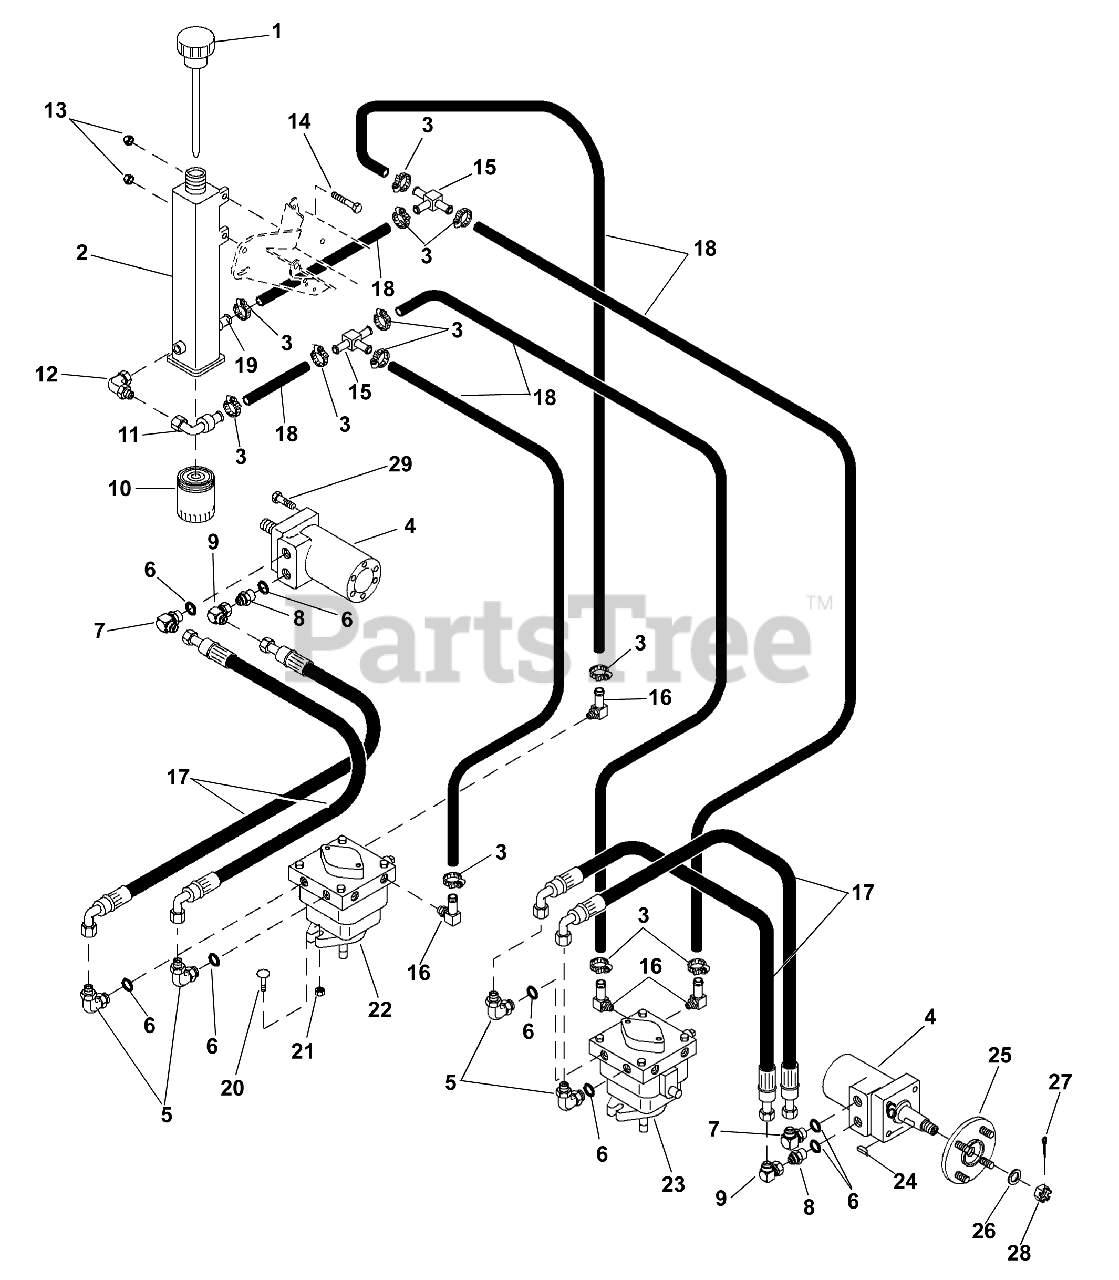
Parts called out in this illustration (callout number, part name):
1	CAP
2	HYDRAULIC RESERVOIR, INC DECAL
3	HOSE CLAMP
4	WHEEL MOTOR
5	FITTING, INCLUDES O-RING
6	O-RING, INCLUDED WITH FITTING
7	ADAPTER, 8MJ-10MB90
8	ADAPTER, HYD ST 7/8 "O" TO 3/4
9	ADAPTER, 3/4 FESW X 3/4MJICX90
10	ELEMENT, OIL FILTER
11	ELBOW FITTING
12	ADPT 2503-6-6
13	NUT-LK-NYL M10-1.5 YWZC
14	BLT-HEX M10 X 1.5X20 GR5 YWZC
15	TEE FITTING
16	FTG-ADPTR .562-18 ST THD
17	HOSE, HIGH PRESSURE
18	HOSE, RETURN 25 FT BLK CUT LEN
19	ADAPTER, STRAIGHT FITTING
20	CARRIAGE BOLT, PUMP MNTNG M10X
21	NUT-LK-NYL M10-1.5 YWZC
22	PUMP, RH
23	PUMP, LH
24	KEY-WDRF .19X.75 HRD #9
25	HUB, REAR WHEEL
26	SHIM, .020X.787X1.102
27	@PIN-CTR .125X2.00 YWZC
28	CASTLE NUT
29	@BLT-HEX .38-16X1.00 GR5 YWZC
